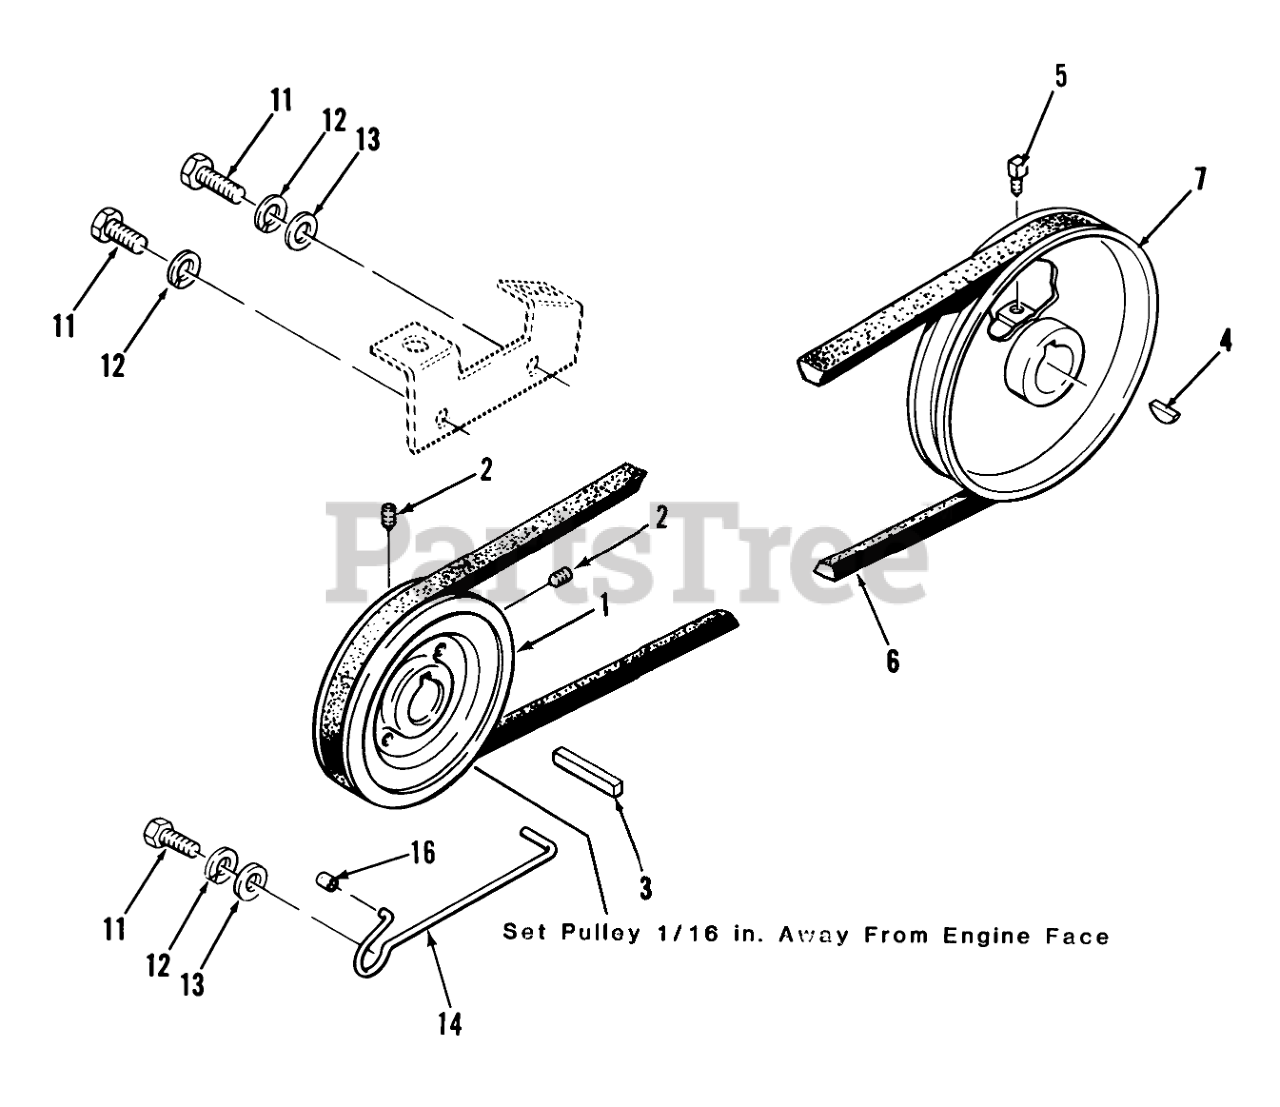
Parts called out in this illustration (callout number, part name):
1	PULLEY
2	Set Screw
4	KEY-HI PRO
5	Set Screw
6	V BELT
7	PULLEY-TRANSMISSION
11	Bolt
12	LOCKWASHER
13	Washer
14	Belt Guide-Bottom 308 Only
